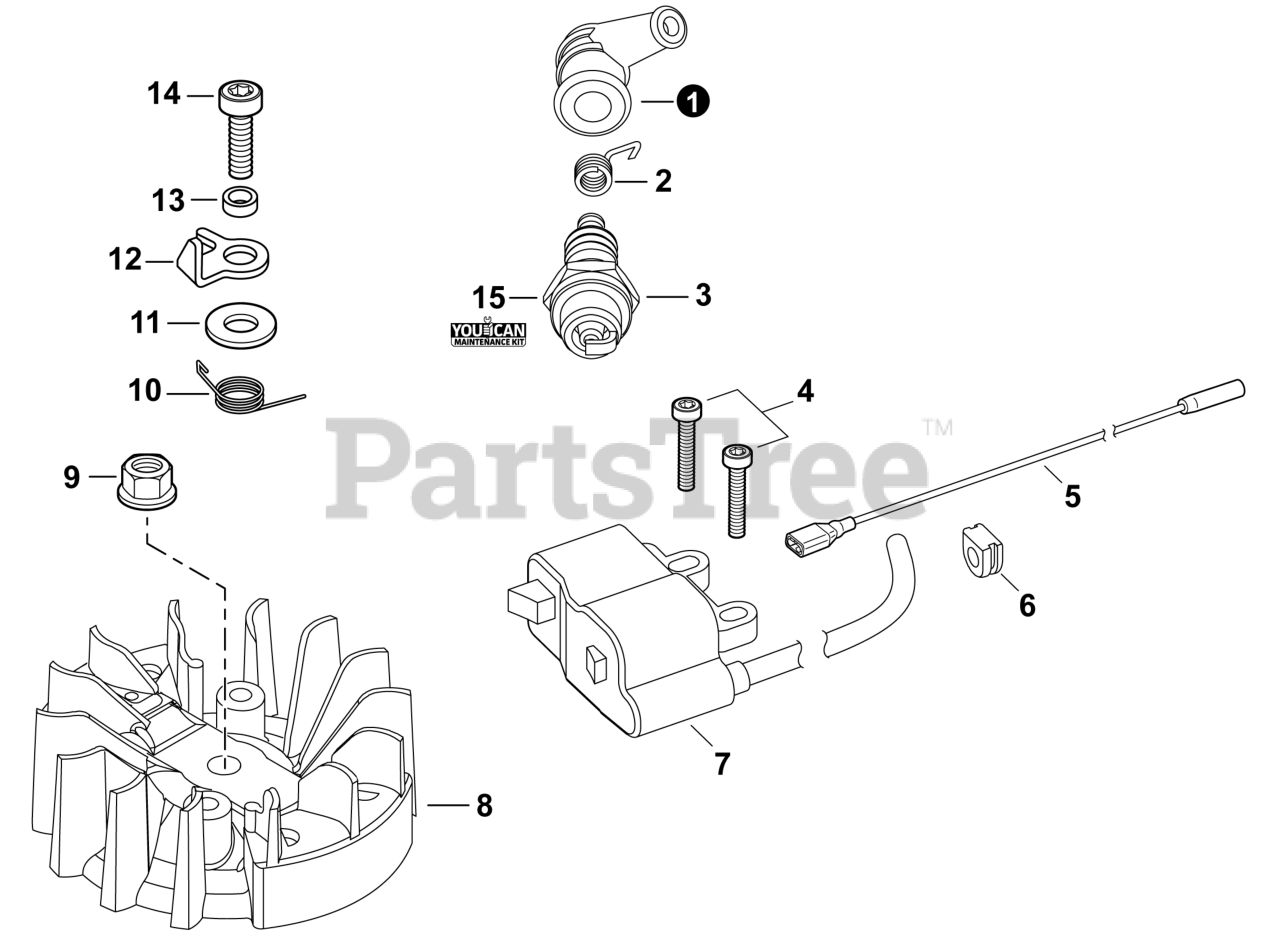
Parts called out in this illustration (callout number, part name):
1	CAP, SPARK PLUG
2	TERMINAL, SPARK PLUG
3	SPARK PLUG - BPMR8Y
4	BOLT, TORX 4x16
5	LEAD L= 85 MM
6	GROMMET
7	COIL, IGNITION
8	FLYWHEEL
9	NUT, FLANGE M6
10	SPRING, TORSION
11	WASHER 5.5x16x0.8
14	BOLT, TORX 5x16
15	TUNE-UP KIT - YOUCANT
